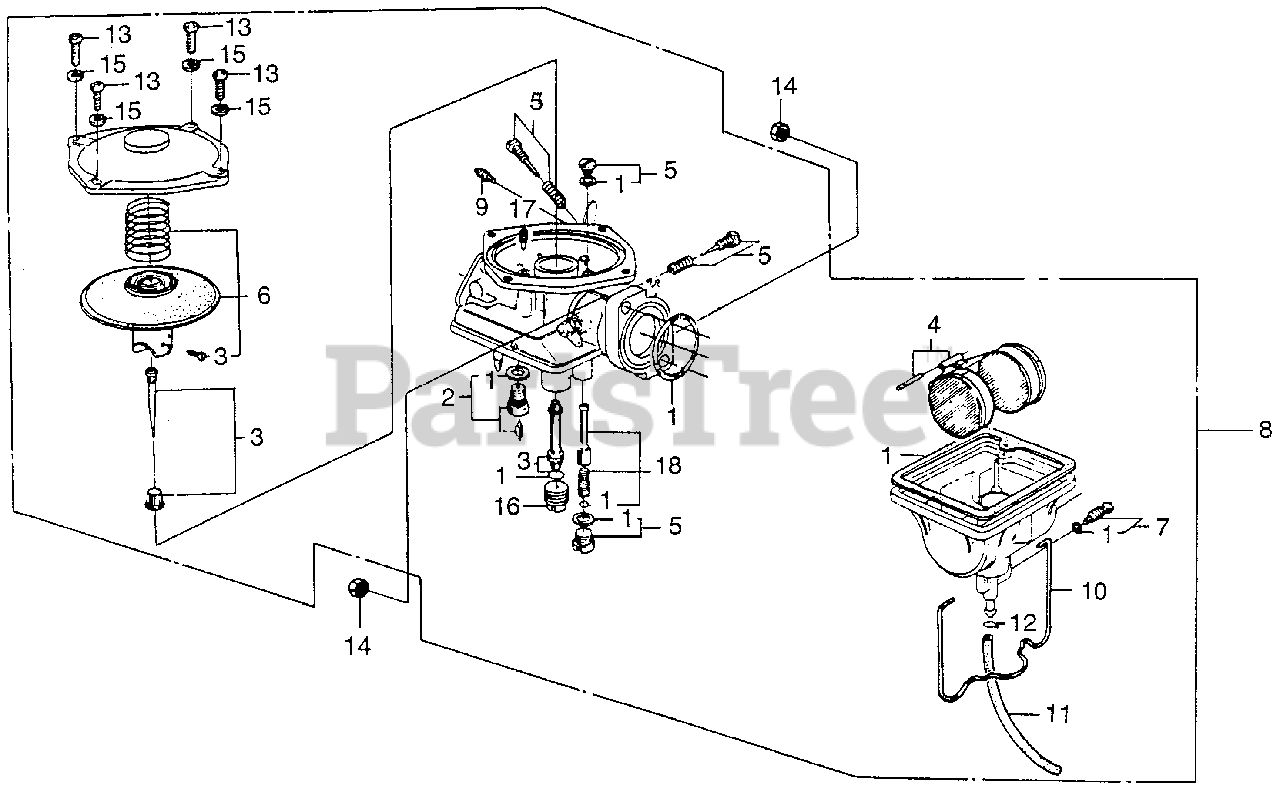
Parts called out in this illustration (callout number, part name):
1	GASKET SET
2	VALVE SET, FLOAT
3	NEEDLE SET, JET (NOT AVAILABLE)
4	FLOAT SET (NOT AVAILABLE)
6	VALVE SET, THROTTLE (NOT AVAILABLE)
7	SCREW SET, DRAIN (NOT AVAILABLE)
8	CARBURETOR ASSY. (NOT AVAILABLE)
10	CLIP, FLOAT CHAMBER SET
11	PIPE, OVERFLOW
11	BULK HOSE, FUEL (3.5X3000) (3.5X150)
12	CLIP B7, TUBE
13	SCREW, PAN (5X12)
14	NUT, HEX. (6MM)
15	WASHER, SPRING (5MM)
16	JET, MAIN (#82)
16	JET, MAIN (#85)
16	JET, MAIN (#92)
16	JET, MAIN (#95)
16	JET, MAIN (#98)
16	JET, MAIN (#100)
18	JET SET, PILOT (#40)
